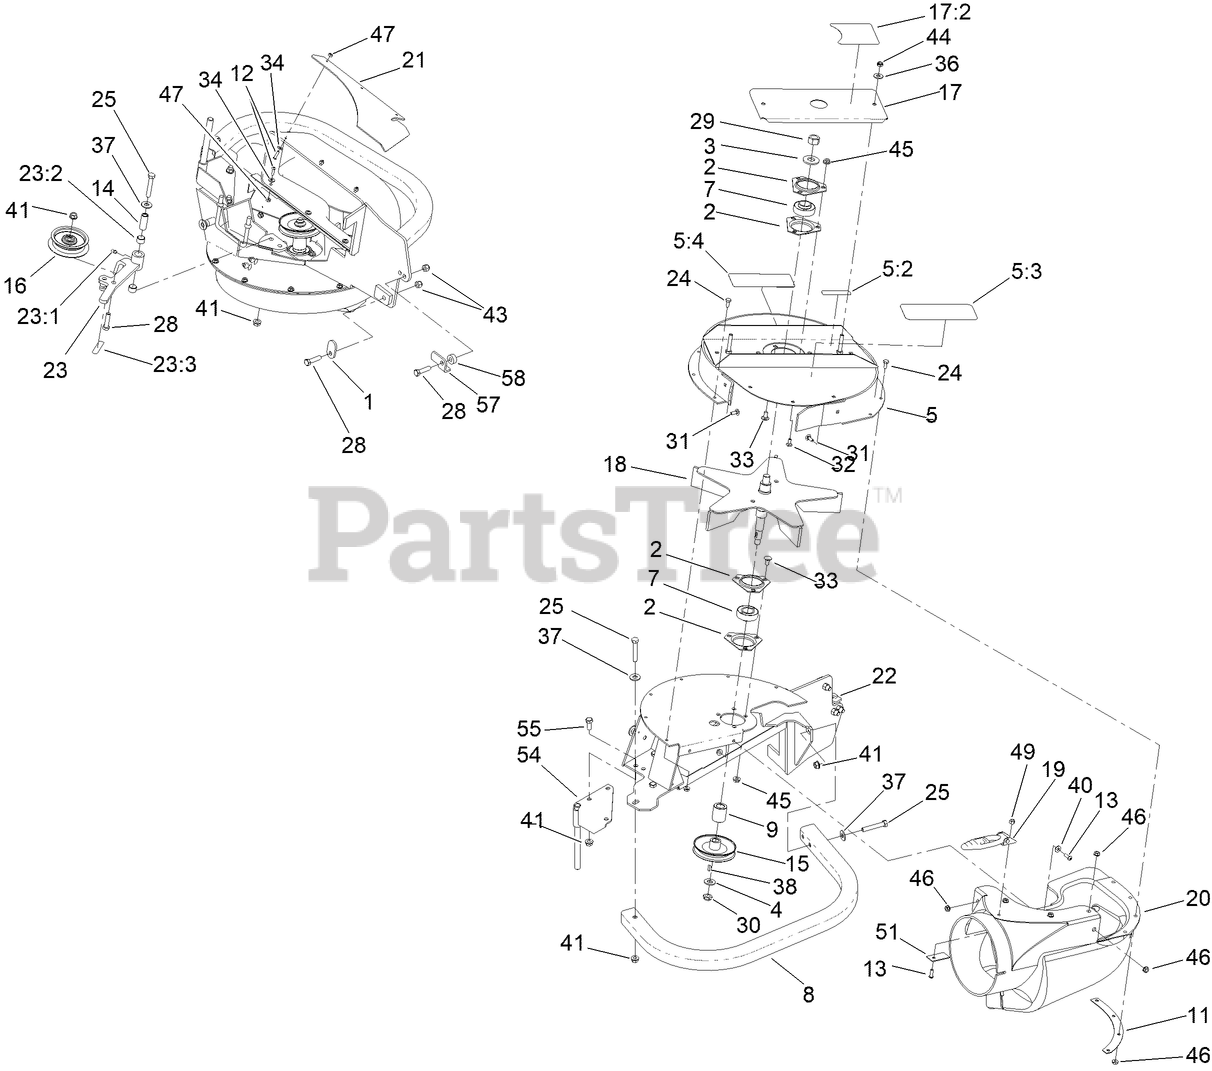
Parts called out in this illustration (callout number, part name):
1	LATCH-CATCHER, GRASS
2	HOUSING-FLANGE
3	WASHER-SPRING
4	WASHER-FLAT
5	HOUSING W/DECAL-UPPER
5:2	DECAL - VIB, PINCH WARNING
5:4	DECAL-WARNING
7	BEARING
9	SPACER
11	PLATE-BACKING, BLOWER
12	SCREW-HSBH
13	SCREW-HSBH
14	BUSHING
15	SHEAVE
16	IDLER-FLAT
17	COVER-BEARING W/DECAL
17:2	DECAL-WARNING
18	IMPELLER
19	LATCH-RUBBER
20	CHUTE-BLOWER
21	PLATE-BOTTOM
22	MOUNT-BLOWER
23	IDLER ARM W/BUSHINGS
23:1	FITTING-GREASE
23:2	BUSHING
23:3	DECAL-WARNING
24	SCREW-HH
25	SCREW-HH
28	SCREW-HH
29	NUT-HEX
30	NUT-LOCK, NI
31	BOLT-CARR
32	SCREW-CARR
33	SCREW-CARR
34	WASHER-FLAT
36	WASHER-FLAT
37	WASHER-FLAT
38	KEY-WOODRUFF
40	WASHER-FLAT
41	NUT-HHF, WHIZ
43	NUT-LOCK, NI
44	NUT-LOCK, NI
45	NUT-HF
46	NUT-HF
47	NUT-LOCK, NI
49	NUT-LOCK, NI
51	PLATE-BACKING
54	PIN-MOUNT
55	SCREW-HH
57	LATCH-STOP
58	SPACER
